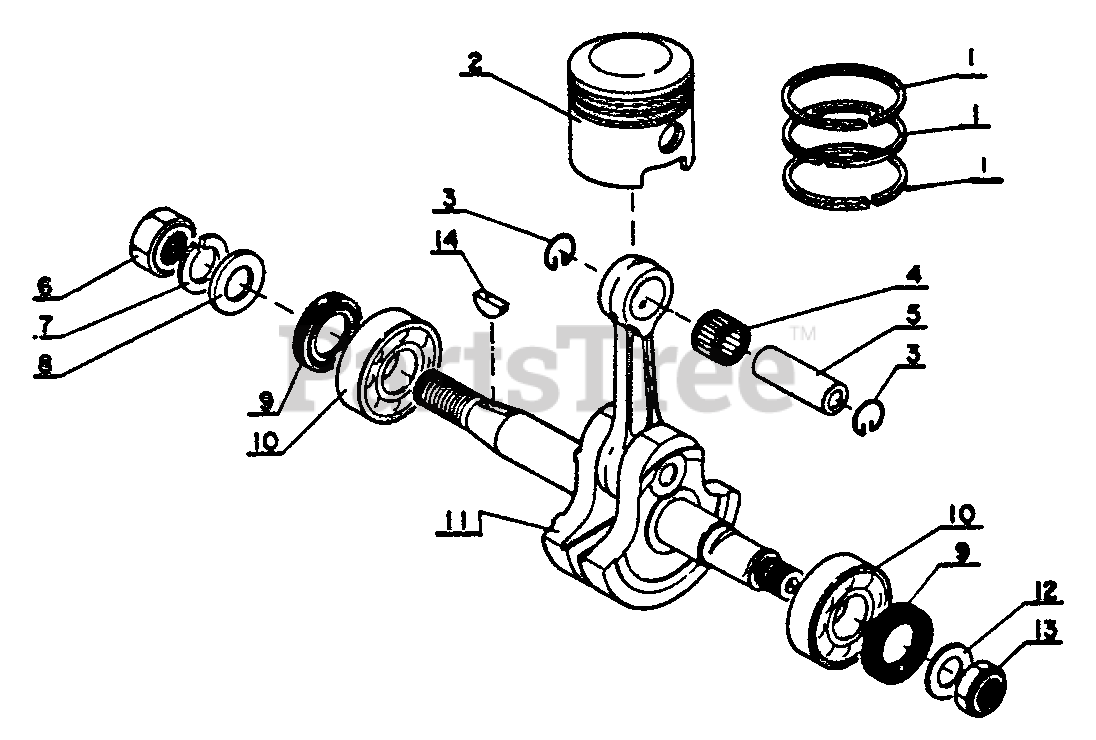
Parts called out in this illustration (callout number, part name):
1	RING, PISTON
2	PISTON
3	RING, SNAP 8
4	BEARING, NEEDLE
5	PIN, PISTON
7	WASHER, SPRING
9	SEAL, OIL
10	BEARING, BALL 6202
11	CRANKSHAFT ASSY
12	WASHER, CLUTCH
